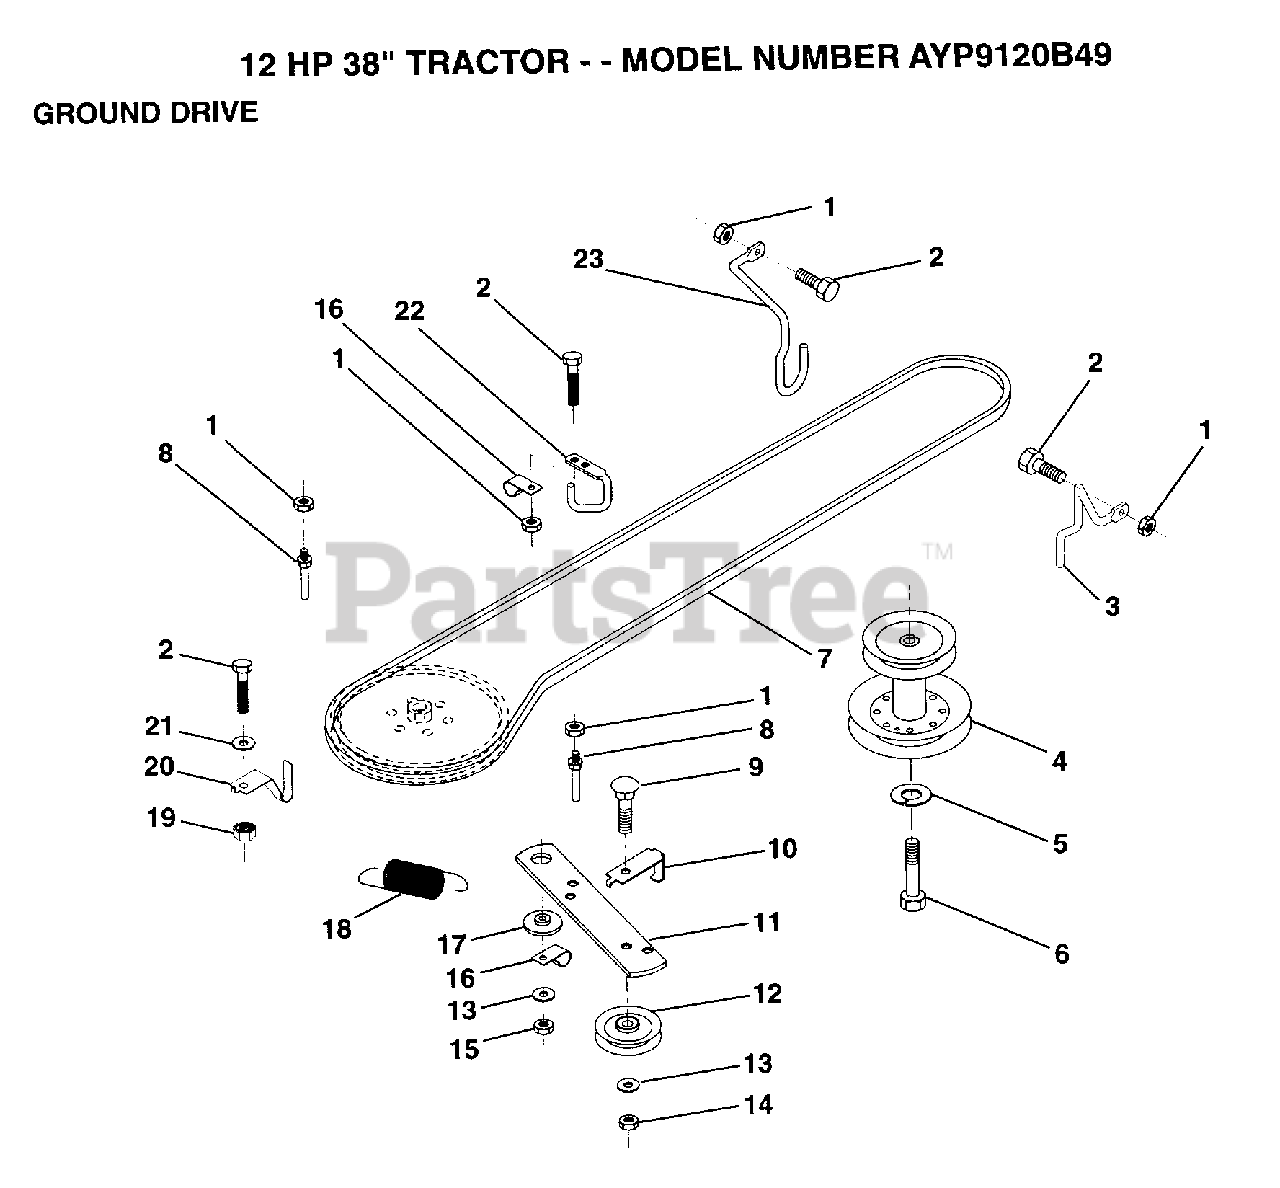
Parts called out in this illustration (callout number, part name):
1	NUT
2	BOLT
3	KEEPER.BELT.FRT.
4	PULLEY.ENGINE.LR
5	LOCKWASHER
6	HEX BOLT
7	BELT
8	"KEEPER,DRIVE BELT"
9	BOLT
10	"KEEP,IDLER DR BEL"
11	ARM IDLER CLUT GD
12	PULLEY.IDLER.FLAT
13	WASHER
14	LOCKNUT
15	NUT
16	CLIP INSULATOR
17	SPACER RETAINER
20	KEEPER.BELT.T/A
21	WASHER
22	"KEEPER,FRA DR BEL"
23	KEEPER.BELT.FRT.L
